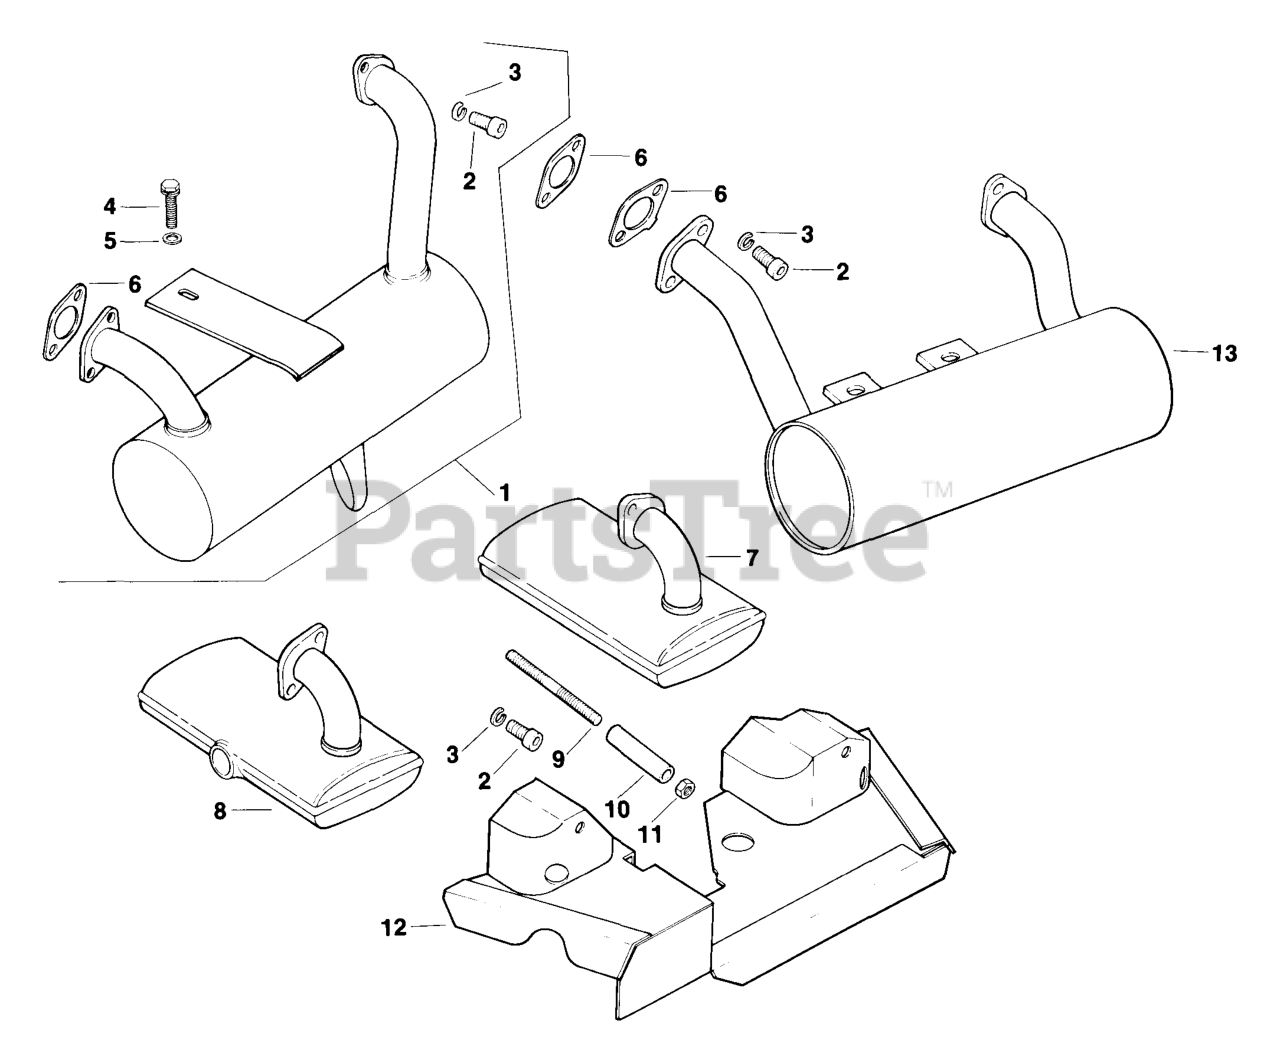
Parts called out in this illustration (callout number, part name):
2	SCREW, HEX SOCKET HEAD CAP USE 25 086 87-S
3	WASHER, SPRING LOCK 5/16"
4	SCREW, SEMS 1/4-20X5/8" USE 25 086 539-S
13	MUFFLER - DISCONTINUED
